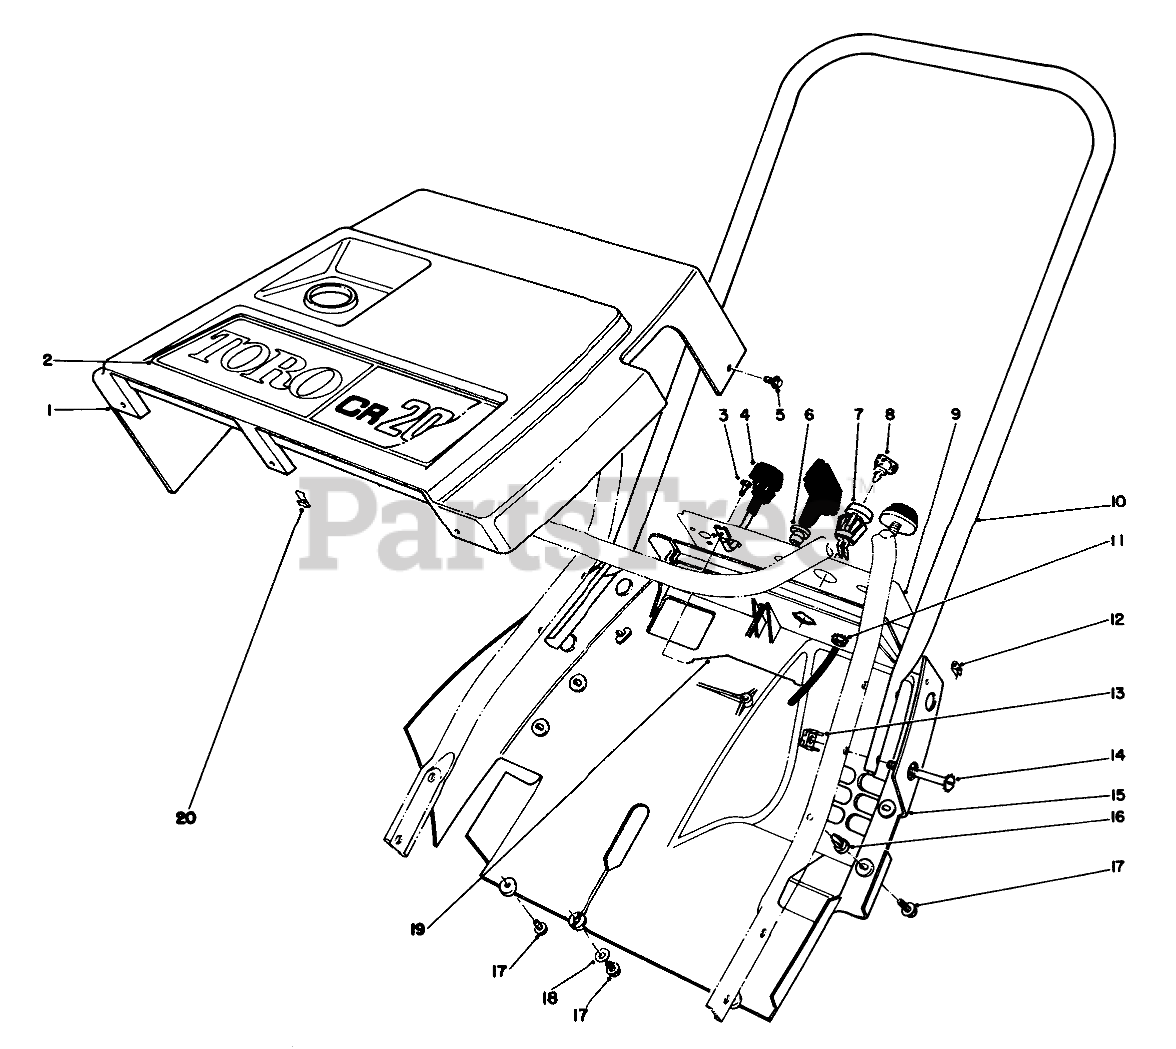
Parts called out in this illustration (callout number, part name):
1	Shroud-Upper
2	Decal-Toro (Model 38110C)
3	SCREW-PLASTITE
4	CHOKE CONTROL ASM
5	SCREW-HWHTF
6	GUIDE-ROPE, STARTER
7	SWITCH
8	KEY-IGNITION
9	Decal-Control Panel (Model 38110C)
10	UPPER HANDLE ASM
11	NUT-KEPS
13	TINNERMAN NUT
14	SCREW-HEX HD SLOT
15	LOWER SHROUD
16	Nut-Push
17	SCREW-HWHTF
18	WASHER-FLAT
19	CONTROL WIRE
20	NUT "U"
